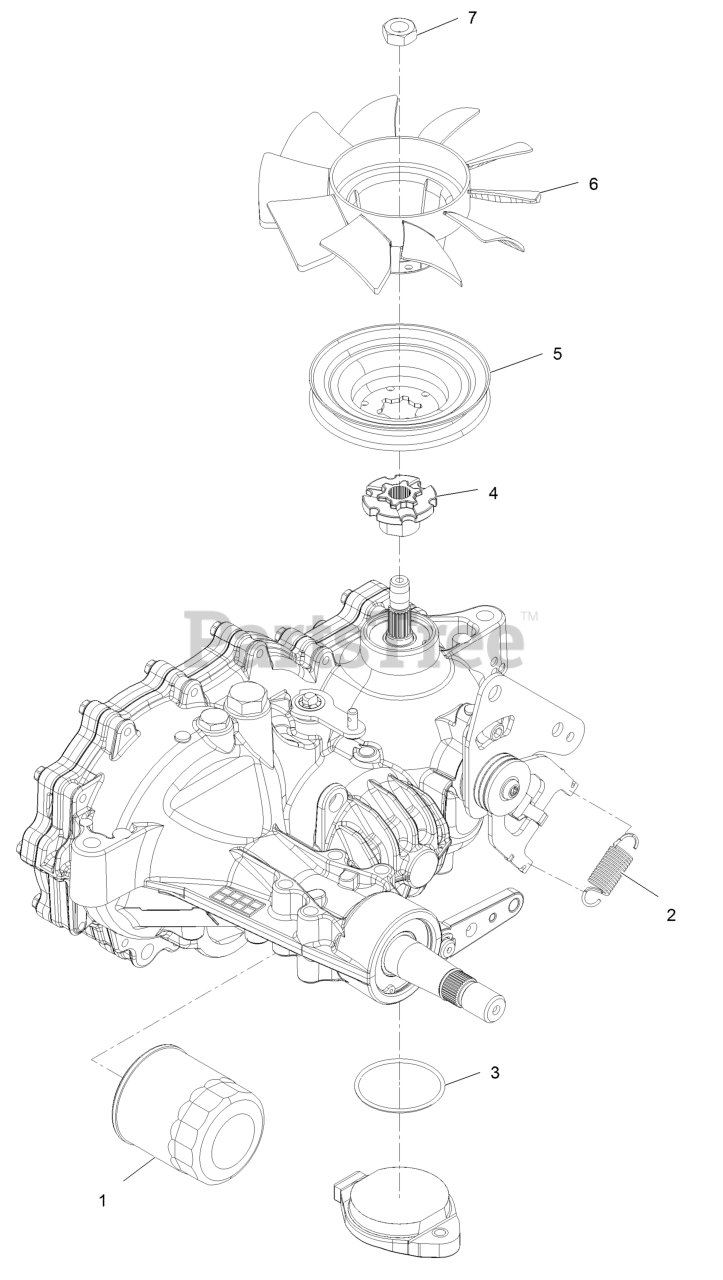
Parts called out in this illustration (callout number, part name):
1	Filter-Hydraulic
2	Spring-Extension
3	O-Ring-Charge Seal Cover
4	Hub-Pulley
6	Fan-7.0 Inch (10 Blade)
99	Brake Shaft Seal Kit
